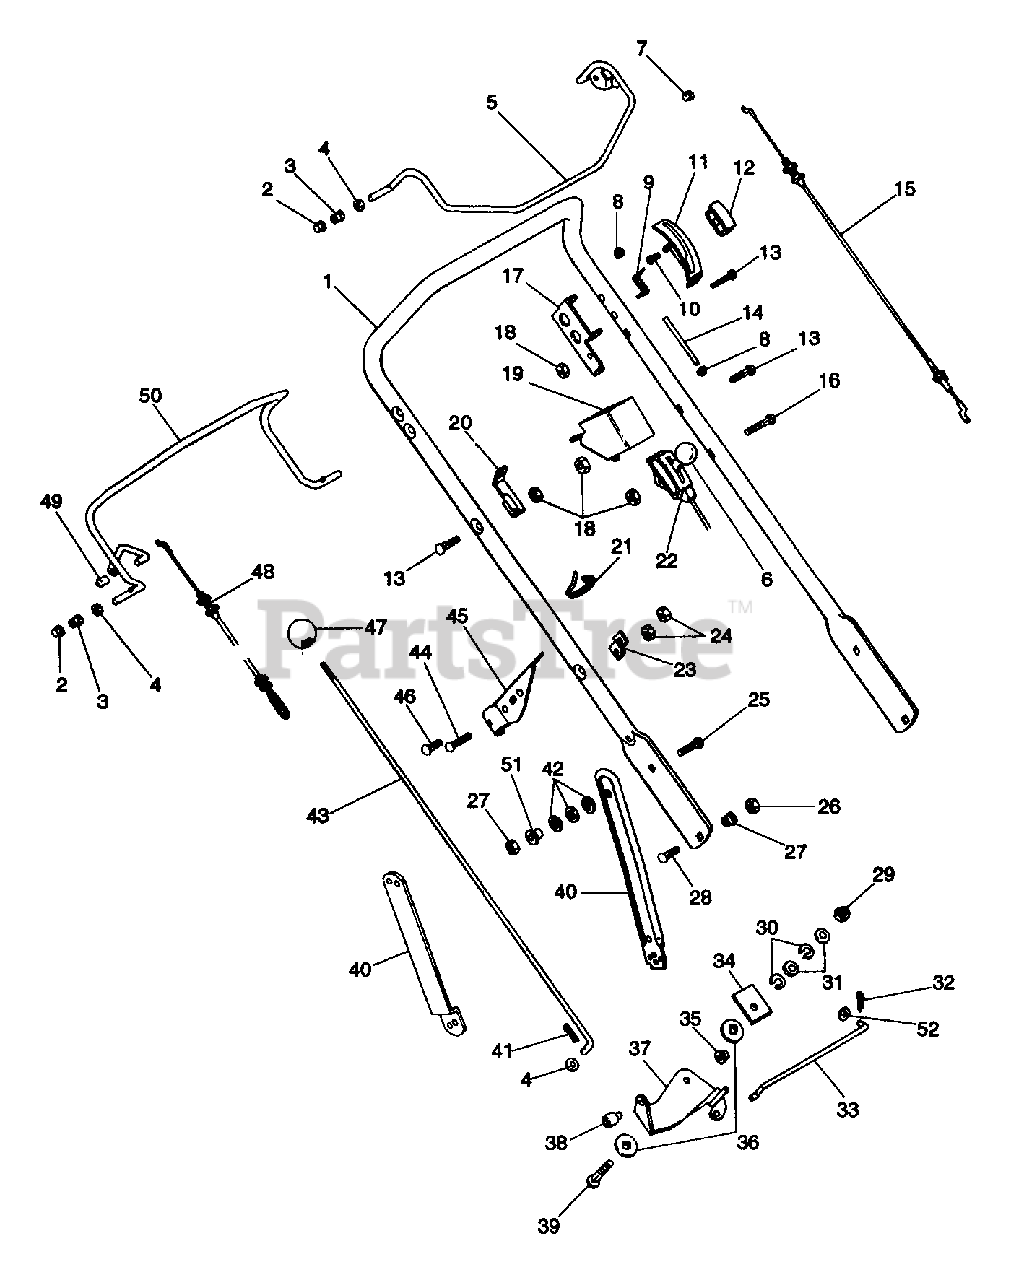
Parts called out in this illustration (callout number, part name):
1	HANDLEBAR
2	NUT-PUSH .312 DIA. PAL
3	BSHG-FLG .325X.444X.440X.560
4	WSHR-FL-STL.344X.688X.065PL
5	ENGINE BAIL
5	BBC BAIL WELDMENT
6	KNOB, CONTROL-THROTTLE
7	PUSH NUT, .25
8	PUSH NUT, .188
9	SG-TORS .062X.28X1.00
10	SCR-TAP 10-24X.375 CRPH PL 1A
11	BBC LATCH
12	KNOB
13	BLT-RDHDSQNK .25-20X1.25 XLGPL
14	PIN,BBC LATCH
15	ENGINE CONTROL CABLE
15	CABLE BBC
16	BLT-RDHDXLSQNK .25-20X2.0 G5YZ
17	BBC LATCH PIVOT
18	NUT-KEPS .250-20
19	SWITCH-CABLE ANCHOR
20	CABLE ANCHOR
20	CABLE ANCHOR-LH
21	CABLE TIE LG 5-1/2
22	CABLE THROTTLE NEGATIVE ACTION
23	BRACE-SPEED CONTROL
24	NUT-LK-CTR .250-20 PL
25	BLT-RDHDSQNK .31-18X1.12 GR5PL
26	NUT-LK-TOP .312-18 GR C PL
27	BSHG, FLG .325X.499X.26X.88
28	BLT-RDHDSQNK.31-18X.88 GR5YWZC
29	NUT-LK-CTR .375-16 GR A PL
30	WSHR-LK .375X.115 HVY PL
31	WSHR-FL-STL.406X.812X.065PL
32	PIN-COTR .06X.50
33	SHIFT LINK
34	PRESSURE FLANGE
35	CAP, 3/8 ROD YWZC
36	FRICTION WASHER
37	BELL CRANK - SPEED CONTROL
38	SWIVEL
39	BLT-RDHDSQNK .38-16X1.50 PL
40	LINK,HANDLE BAR ADJUST LH
40	LINK,HANDLE BAR ADJ RH
40	HANDLEBAR BRACKET
41	PIN-HAIR INT .08X.18X1.18
42	WASHER,BELLEVILLE SPRING
43	ROD-SPEED CONTROL
44	BLT-RDHDSQNK .25-20X1.38SHT PL
45	BRACKET-SPEED CONTROL
46	@BLT-RHDSSQNK .25-20X.38 G2YZ
47	KNOB, BALL 5/16-18 X 1.5
48	TRACTION CABLE
49	CAP, VINYL, .25 ID
50	TRACTION BAIL-COATED
51	BSHG-FLG .325X.500X.513X.875
52	WSHR-FL-STL.281X.62X.065 PL
